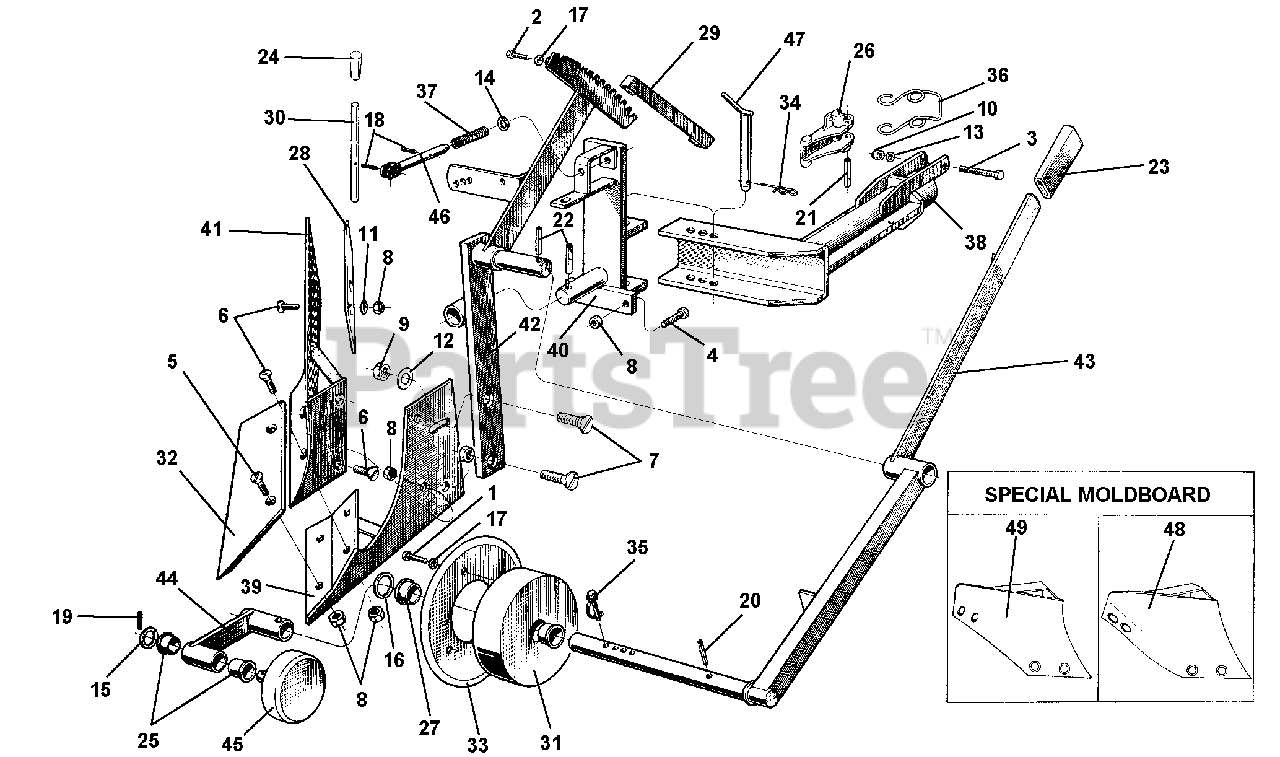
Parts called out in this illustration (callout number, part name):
1	SCREW M8 X 16
2	SCREW M8 X 12
3	SCREW M8 X 60
4	SCREW M10 X 30
5	SCREW M10 X 22
6	SCREW M10 X 25
7	SCREW M12 X 35
10	NUT, SELF LOCKING M8
11	FLAT WASHER 10.5 X 21
12	WASHER, FLAT 13
13	WASHER, FLAT
14	WASHER, FLAT
15	WASHER, FLAT
16	WASHER, FLAT 25
17	WASHER, LOCK 8.4
18	PIN, LOCKING 4 X 20
19	PIN, LOCKING
20	PIN, LOCKING 6 X 40
29	LEVER PROTECTOR
30	ADJUSTING LEVER
31	SKIM COULTER
38	PLOW COUPLING
39	MOLDBOARD SUPPORT
40	CENTRAL SUPPORT COUPLING
42	CENTRAL SUPPORT
44	WHEEL SUPPORT
47	COUPLING PIN
48	SPECIAL MOLDBOARD
49	SPECIAL MOLDBOARD
